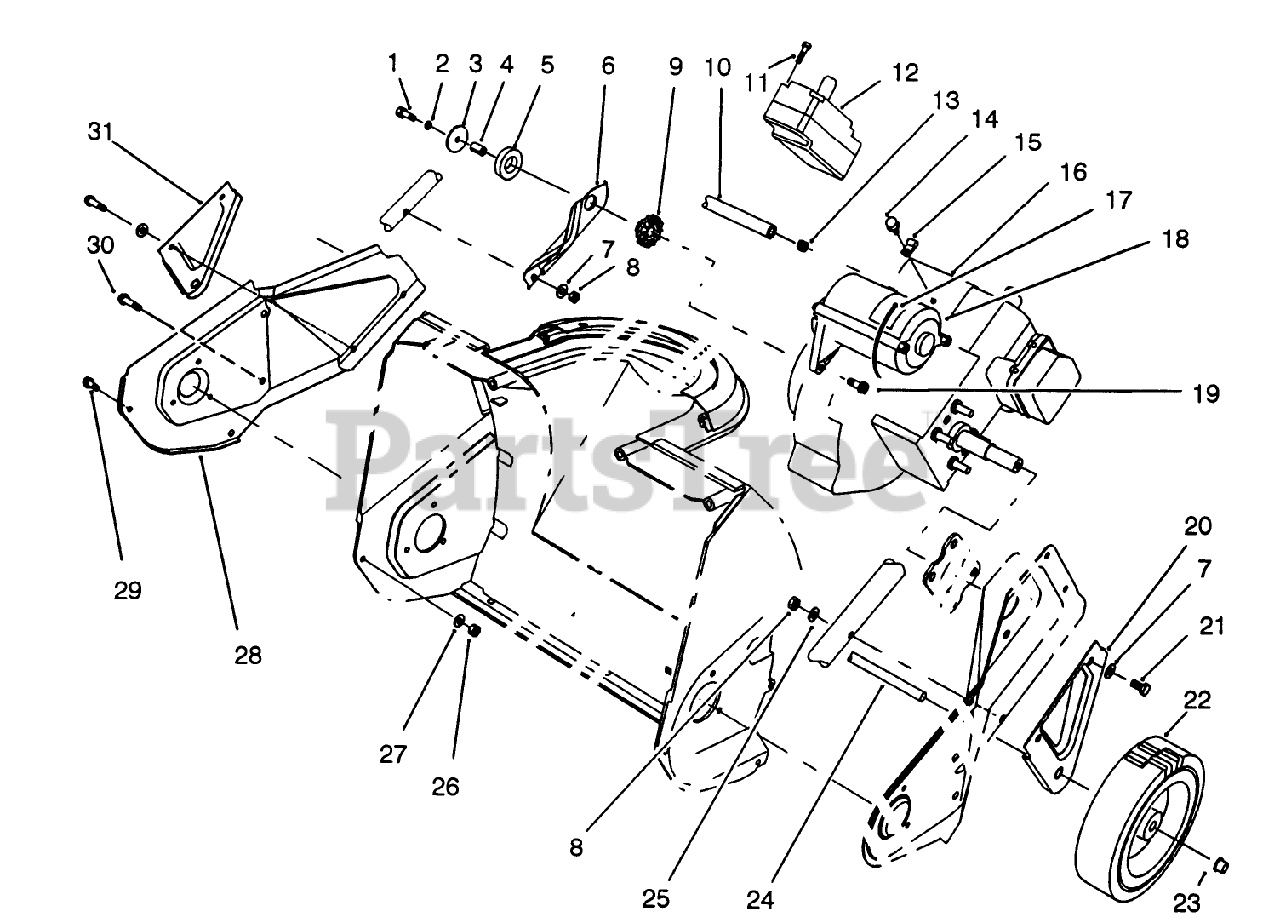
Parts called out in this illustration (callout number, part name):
1	SCREW-HH
2	WASHER-LOCK
4	SPACER-TUBULAR
7	WASHER-FLAT
8	NUT-LOCK, NI
9	BUSHING-ISOLATOR
10	LINE-GAS
11	SCREW-PLASTITE
12	HOUSING-MOTOR AND SWITCH
14	SCREW-HWH
15	CLAMP
17	TIE-CABLE
19	SCREW-HH, TORX
21	SCREW-HH
22	WHEEL
23	NUT-PUSH
24	AXLE SHAFT
25	WASHER
26	NUT-LOCK, NI
27	WASHER-FLAT
29	SCREW-SHWH
30	SCREW-PLASTIC
